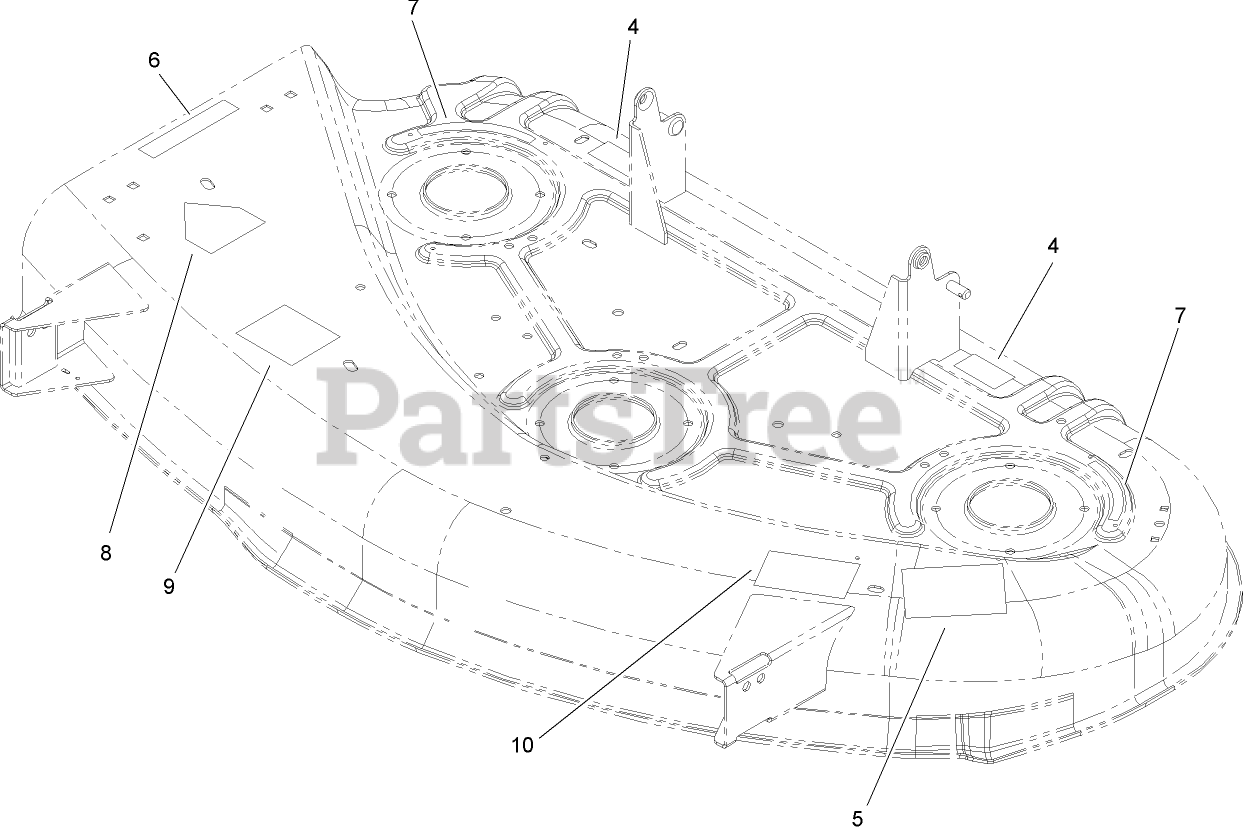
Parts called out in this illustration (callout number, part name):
4	DECAL-WARNING
5	DECAL-DANGER, THROWN OBJECT
6	DECAL-DANGER, DEFLECTOR
7	DECAL-DANGER, SHIELD
8	DECAL-DANGER
9	DECAL-INSTALLATION, BELT
10	DECAL-ADJUSTMENT, WHEEL
